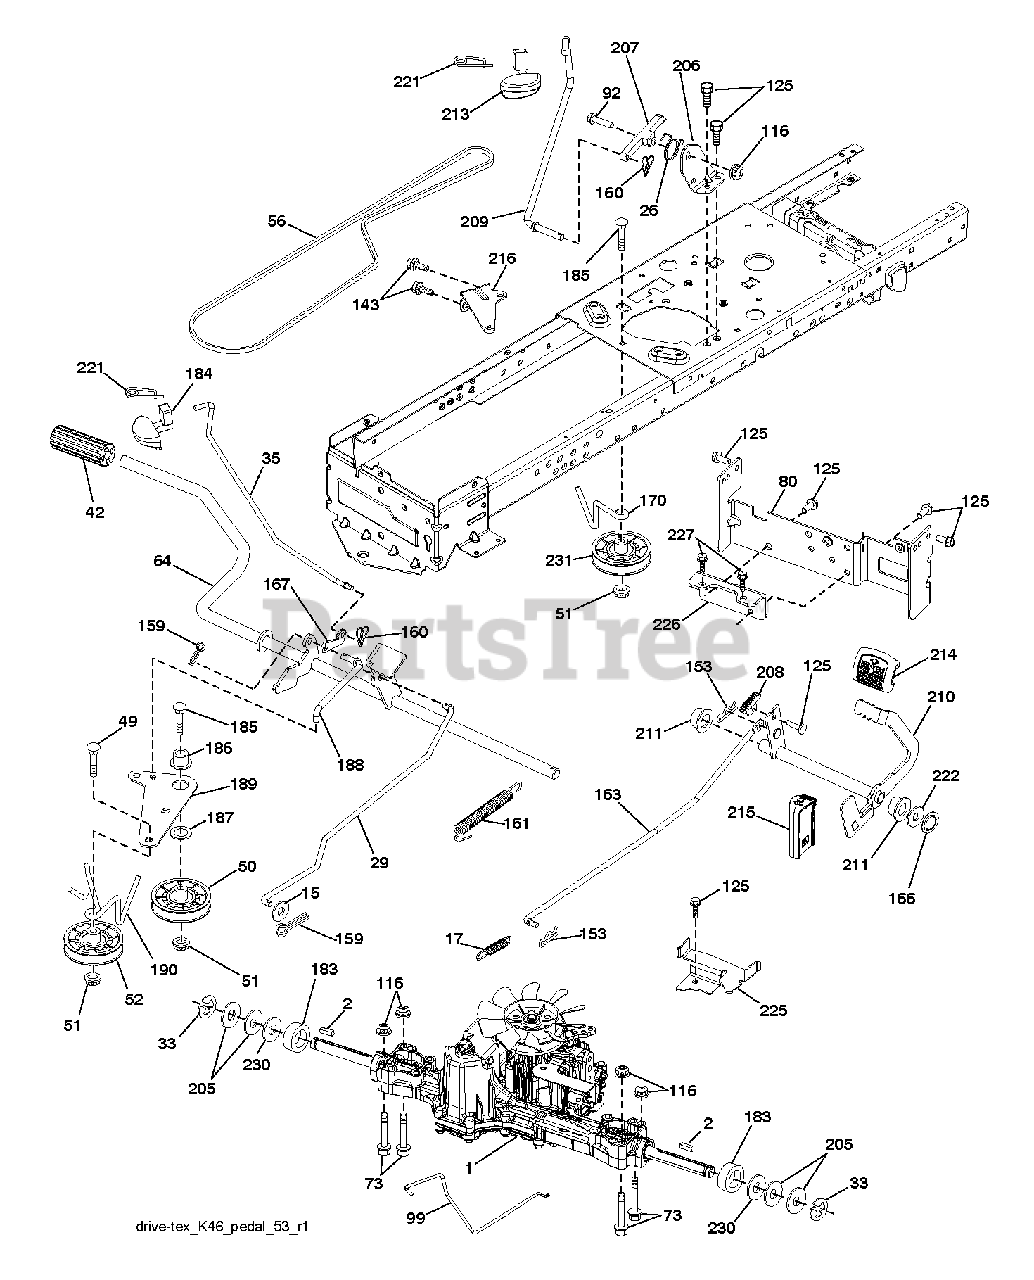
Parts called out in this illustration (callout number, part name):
2	SQUARE KEY
17	SPRING.BRAKE.K46.GREEN
26	SPRING.RETURN.CRUISE
29	ROD.BRAKE.K46
33	E-RING LT
35	ROD.BRAKE.PARKING.LT.T
49	BOLT
50	IDLER.FLAT.910.OFFSET
51	NUT LOCK FLG 3/8-16 UNC
52	IDLER.V-GROOVE.910.OFFSET
56	V-BELT.MOWER.92.40.42/K46
64	SHAFT.ASM.PEDAL.BRK.CNTR
80	STRAP.TORQUE.K46.K57R.TT
92	BOLT
99	ROD.SPRING.BYPASS.K46.LT.Z
116	NUT LOCK HEX FLANGE 5/16-18
125	SCREW
143	SCREW LT
159	COTTER PIN
160	RETAINER CLIP
161	SPRING, RETURN LT
163	ROD.CONTROL.PEDAL.K46
166	NUT.PUSH.625
167	LATCH.BRAKE.SPRING
170	KEEPER.CENTER SPAN.1.688
183	SPACER AXLE
184	HANDLE.PARKING.BRAKE.LTTEX.667
186	SPACER.RETAINER
187	WASHER 12/32X2X10GA
188	LINK.CLUTCH.GROUND.DRIVE
189	BELLCRANK.GROUND.DRIVE.TEX.
190	KEEPER.BELLCRANK.DRIVE
206	BRKT.MOUNT.LATCH.CRUIS
207	LATCH.CONTROL.CRUISE
208	GEAR.SECTOR.CONTROL.CR
210	ROCKER.ASM.PEDAL.CONTR
211	BEARING.NYLON
213	HANDLE.CONTROL.CRUISE.ELTE
214	PEDAL.FORWARD.PAD.TEX
215	PEDAL.REVERSE.TEX.GT.4
216	BRACKET.PULLEY.IDLER.W/TEX
221	RETAINER.SPRING.CLIP.H
222	WASHER 21/32 X 1-1/4 X 10 GA.
225	KEEPER.BELT.TRANSAXLE.K46
226	BRACKET.MOUNT.TORQUE.K46.TLT
227	Screw, Lt
230	WASHER.HARDENED
231	IDLER.V-GROOVE.1.688.OFFSET
